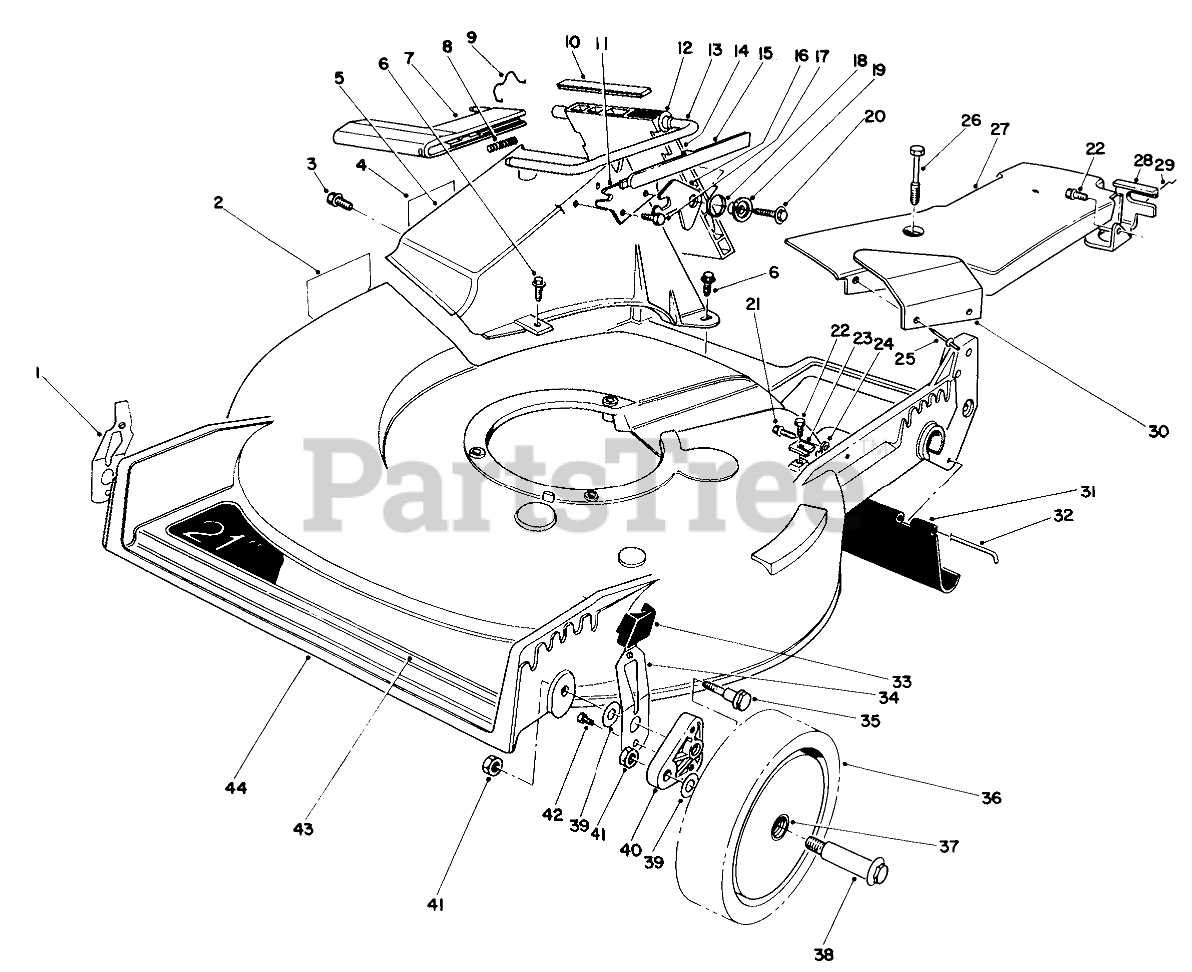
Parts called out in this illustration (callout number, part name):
1	RH SPRING ARM ASSEMBLY
2	DECAL-DANGER
3	SCREW AND WASHER ASM
4	DECAL - DANGER
5	Tunnel-Discharge (Incl. Ref. #4)
6	SCREW-HWH
7	Handle-Door
8	Spring
9	DOOR RET SPRING
10	Cover-Door
11	DOOR LATCH PLATE
12	BUSHING-NYLON
13	DOOR ROD +
14	Door-Discharge
15	Cover-Handle
16	SAFETY LATCH
17	SCREW-PLASTITE
18	TORSION SPRING
19	DOOR SPACER
20	SCREW-HWH
21	SCREW
22	SCREW-HWHTF
23	CLAMP-CABLE
24	CLAMP-CABLE
25	RIVET-HEAD, FLAT
26	SCREW-HHFTF
27	Belt Cover Assembly (Incl. Ref. #25 & 30)
28	Bracket-Traction Adj.
29	RETAINER-CABLE
30	HEAT SHIELD
31	SHIELD-TRAILING
32	ROD-SHIELD
33	KNOB-ARM
34	LH SPRING ARM ASSEMBLY
35	SCREW-SHOULDER
36	Wheel & Tire Assembly (Incl. Ref. #37)
37	BUSHING
38	WHEEL BOLT
39	WASHER
40	ARM-PIVOT, FRONT
41	Nut
42	SCREW-HWH
43	DECAL - DECK
44	Housing Assembly
